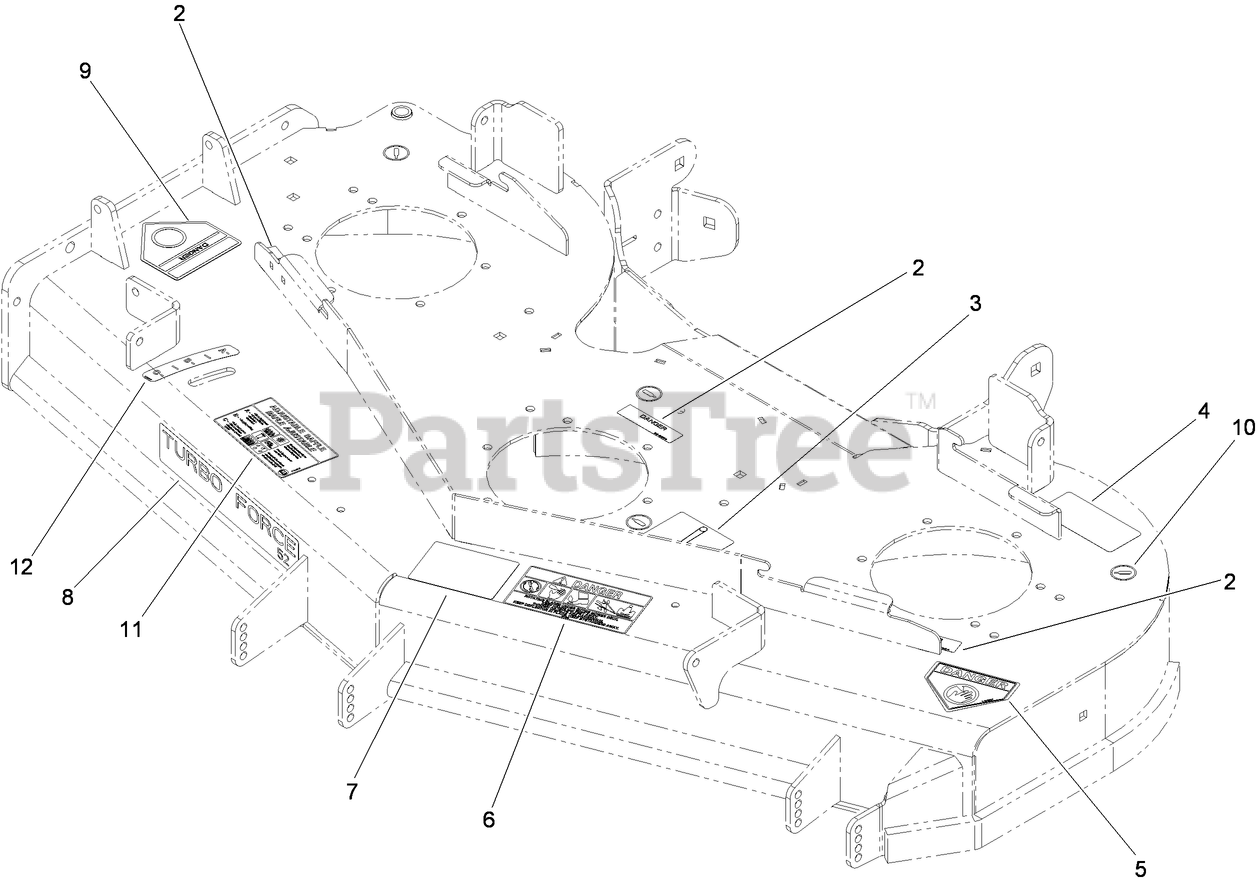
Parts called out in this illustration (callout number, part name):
2	DECAL-COVER, MISSING
3	DECAL-ROUTING, DECK BELT
4	DECAL-TORQUE
5	DECAL-DANGER
6	DECAL-DANGER, THROWN OBJECT
7	DECAL-SCALP, ANTI
9	DECAL-DANGER
10	DECAL-GREASE
11	DECAL-ADJUSTMENT, BAFFLE
12	DECAL-SETTING, BAFFLE
